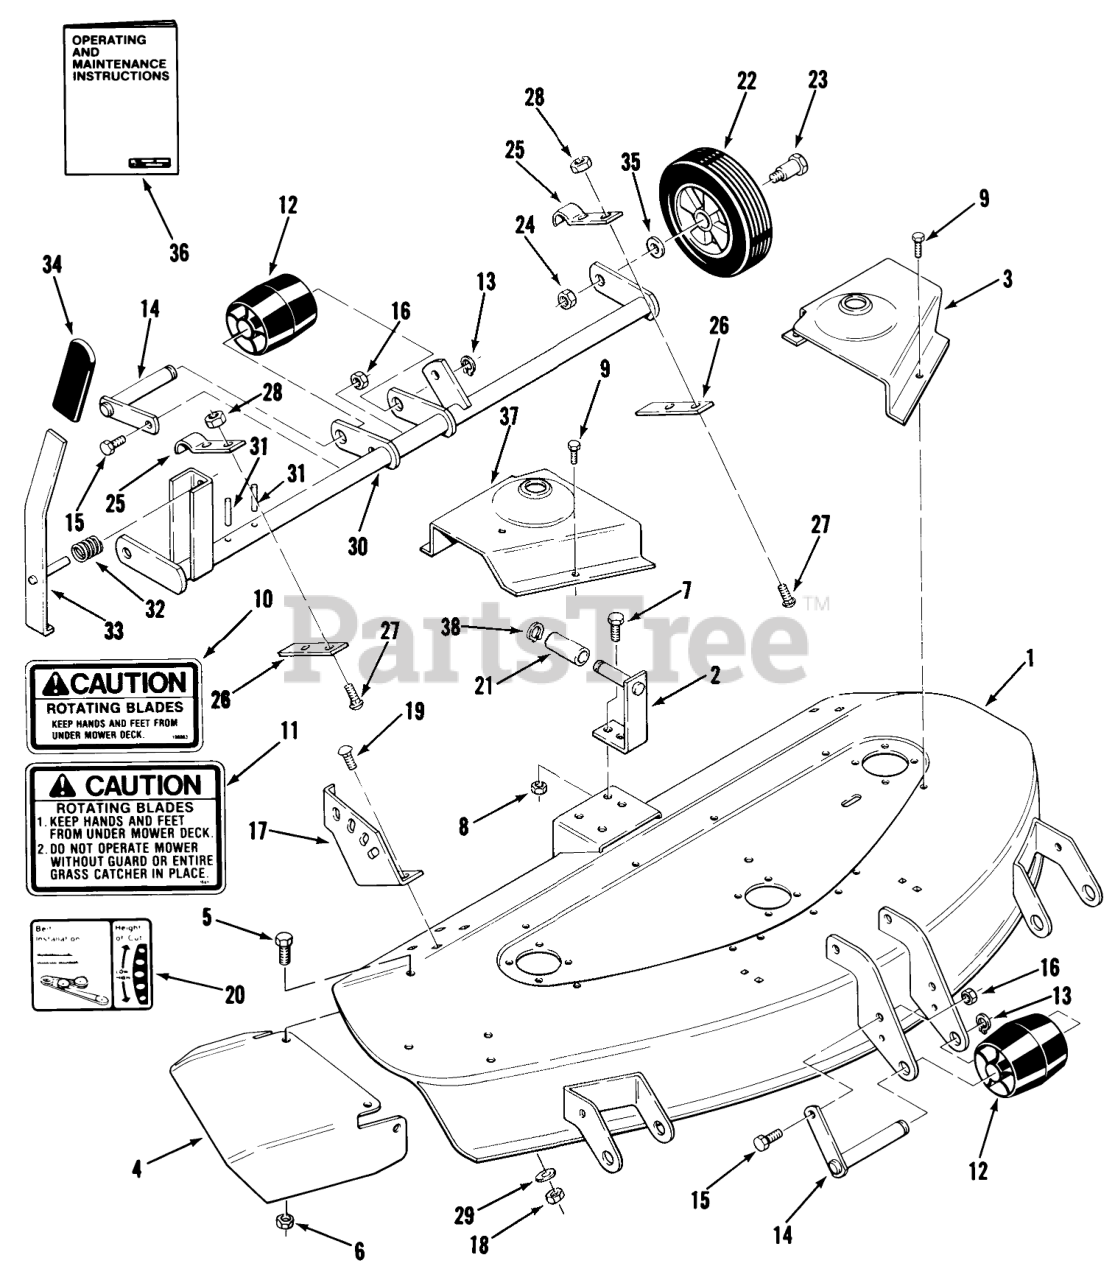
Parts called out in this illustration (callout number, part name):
1	Deck
2	Bracket Guide
3	COVER-BELT LH R
4	Chute Extension
5	Bolt
6	Nut
7	BOLT
8	Nut
9	Bolt
10	Caution Decal
11	DECAL
12	Roller
13	Retaining Ring
14	Roller Shaft
15	H H C S
16	Nut
17	Quadrant
18	Nut
19	Bolt-Carriage
20	DECAL-HEIGHT BELT
21	SPACER
22	Wheel 6 x 1.75
23	BOLT-SHOULDER
24	Nut
25	Machine Bolt
26	Bar
27	Bolt
28	NUT
29	Washer
30	Gage Wheel Support
31	PIN-SPIROL
32	SPRING-COMPRESSION
33	LEVER ASSY R
35	WASHER
36	Operating and Maintenance Instructions
37	COVER-BELT RH R
38	Snap Ring
